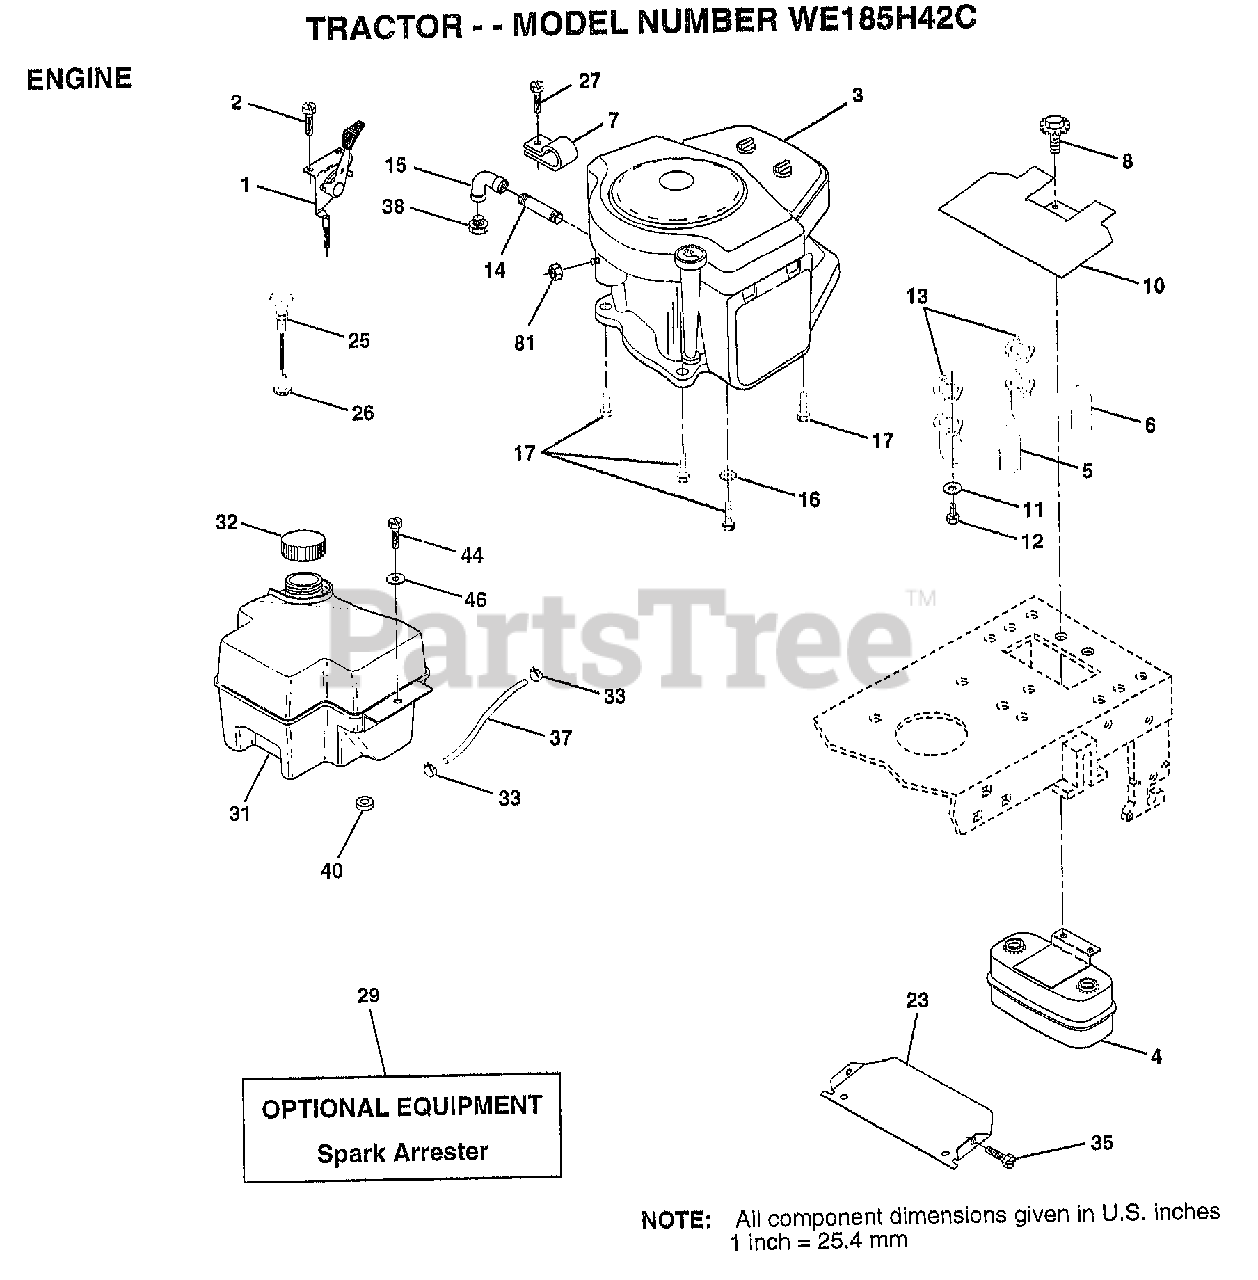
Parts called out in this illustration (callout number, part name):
1	CONTROL THRT 35.5
2	SCREW LT
4	MUFFLER.TW.LOTONE
5	EXHAUST.B&S.18.LH
6	EXHAUST.B&S.18.RH
7	CLAMP.TUBE.DBL.EN
8	BOLT.5/16-18.UNC
10	SHIELD.HEAT.
11	LOCKWASHER
13	GASKET MUFFLER
14	PIPE NIPPLE LT
15	ELBOW
16	LOCKWASHER
17	SCREW LT
23	SHIELD-HEAT
25	CONTROL.CHOKE.37
26	"NUT,KEPS 3/8-24IM"
27	"SCREW-TT,10-32 FL"
32	CAP ASM FUEL
33	HOSE CLAMP
35	SCREW
37	LINE FUEL
44	SCREW HEX CRT
46	WASHER
81	NUT
